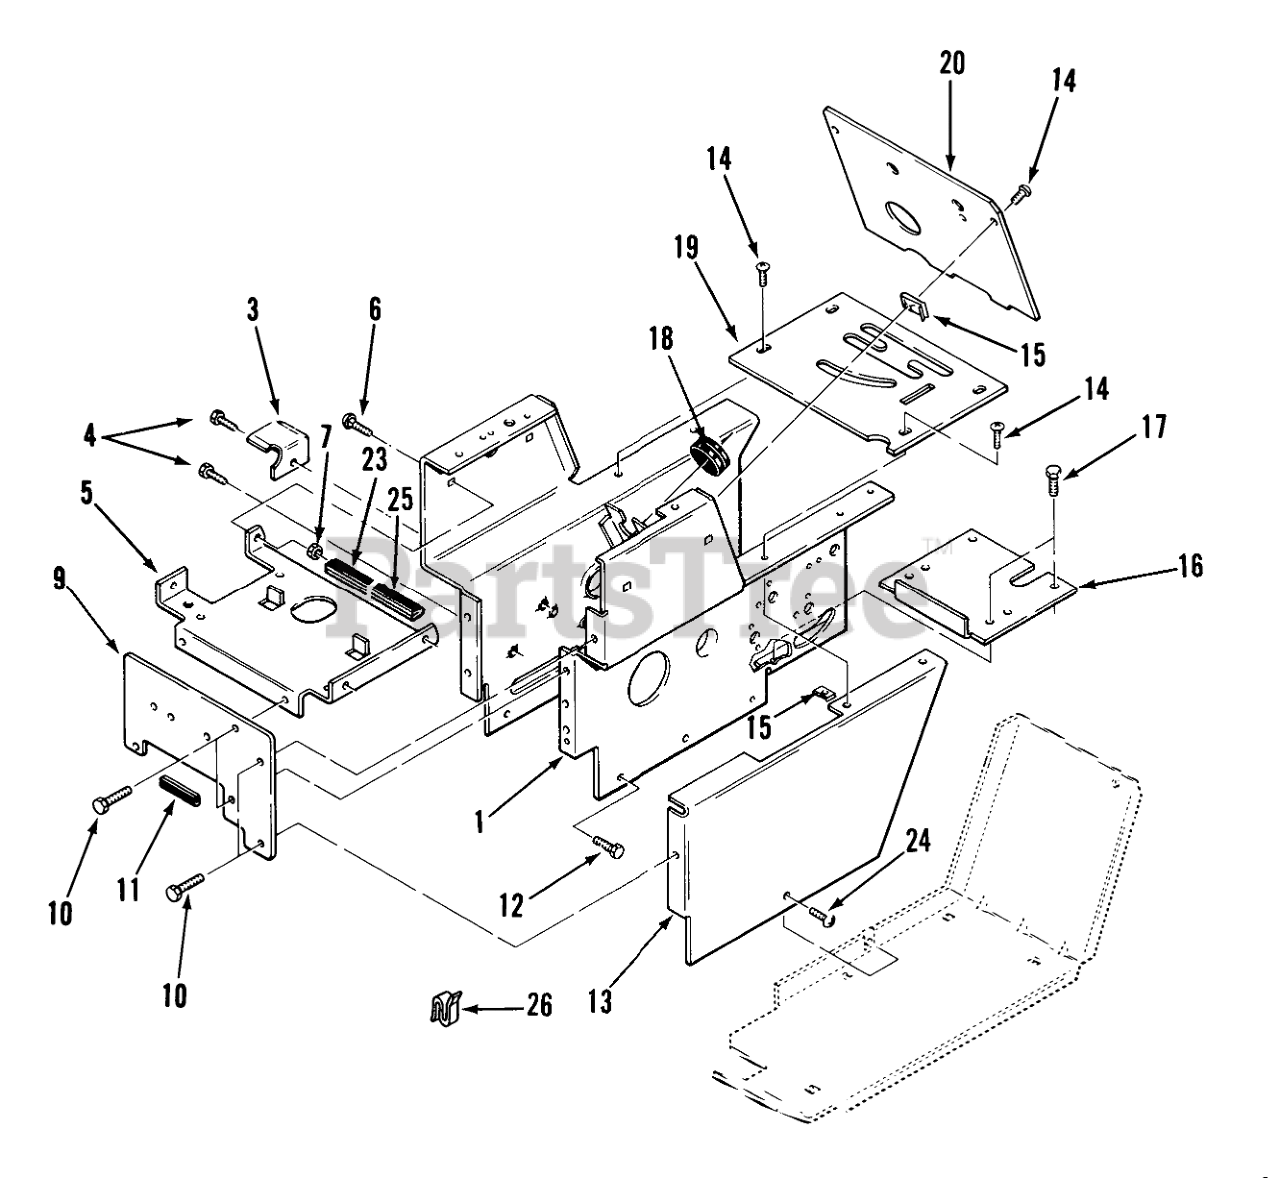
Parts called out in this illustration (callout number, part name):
1	Hoodstand
3	Belt Bracket
4	SCREW
5	SUPPORT-BATTERY B
6	CARRIAGE BOLT -4
7	Nut
9	Front Plate
10	SCREW
11	EDGE TRIM 2" 102896
12	SCREW
13	Side Cover LH
14	SCREW-PPH
16	Cover-Dust
17	SCREW
18	GROMMET
19	PLATE SHIFT PATTE B
20	PLATE HOODSTAND B
23	EDGE TRIM 5" OF 102896
24	Screw
25	EDGE TRIM 2" 102896
26	SPEED CLIP
